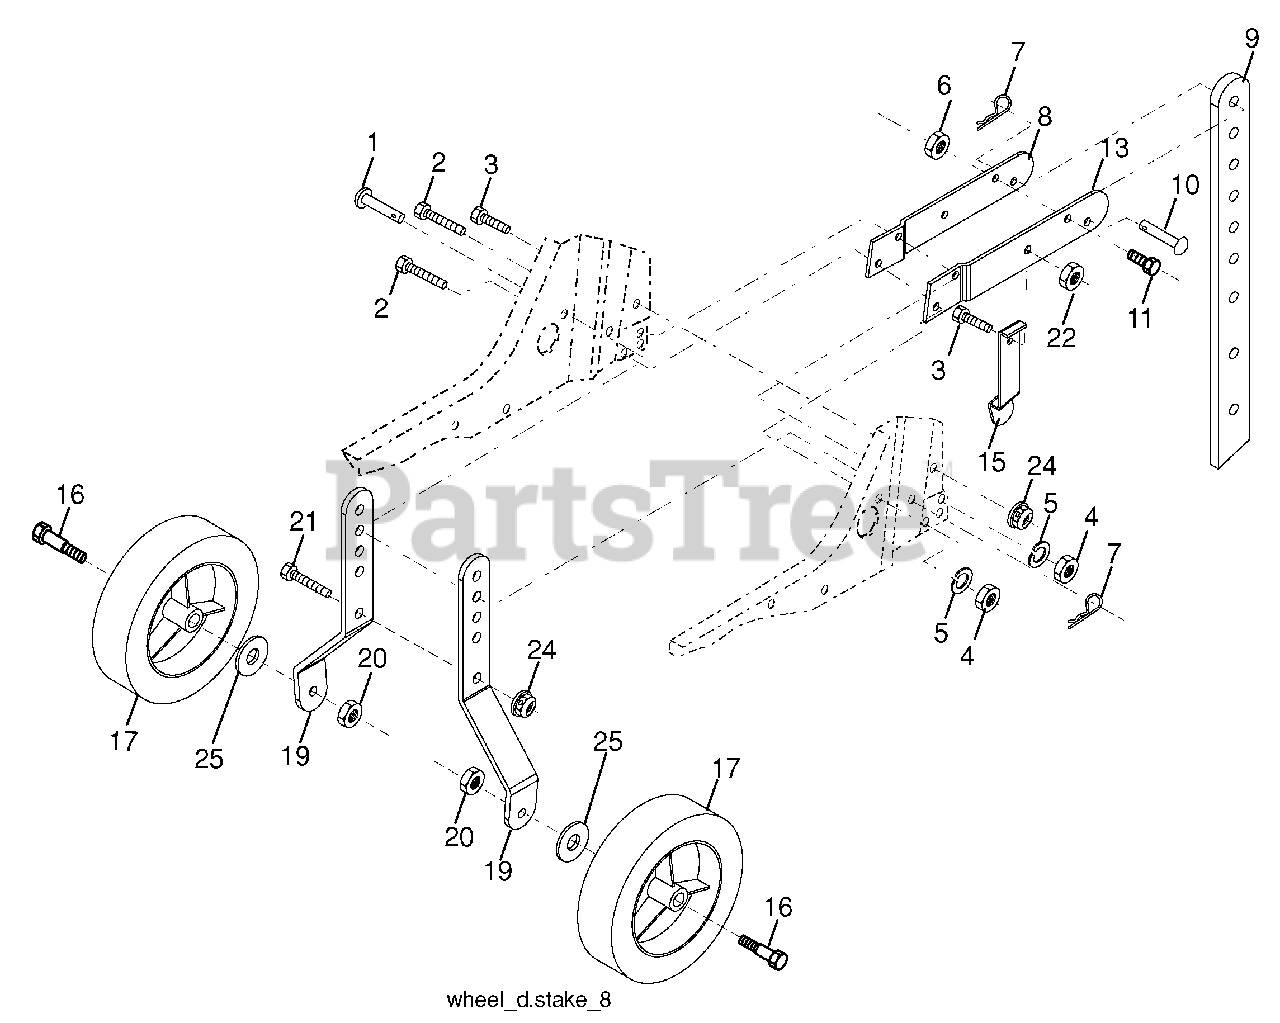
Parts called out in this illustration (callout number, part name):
1	Pin, Clevis
2	Bolt, Hex Head 5/16-18 x 1-1/4
3	Bolt, Hex Head 5/16-18 x 3/4
4	Nut, Hex 5/16-18
5	Washer, Lock 5/16
6	Locknut, Washer Insert 3/8-16
7	Clip, Hairpin
8	Support, Depth Stake, R.H.
9	Stake, Depth
10	Pin, Clevis
11	Bolt, Hex Head 3/8-16 x 1-3/4
13	Support, Depth Stake, L.H.
15	Spring, Stake
16	Bolt, Shoulder
17	Wheel
19	Bracket, Wheel
20	Nut, Hex, Crownlock 3/8-16
21	Bolt, Hex Head 5/16-18 x 1
22	Locknut, Washer Insert 5/16-18
24	Nut, Hex, Flangelock
25	Washer, 17/32 x 7/8 x 16 Ga.
